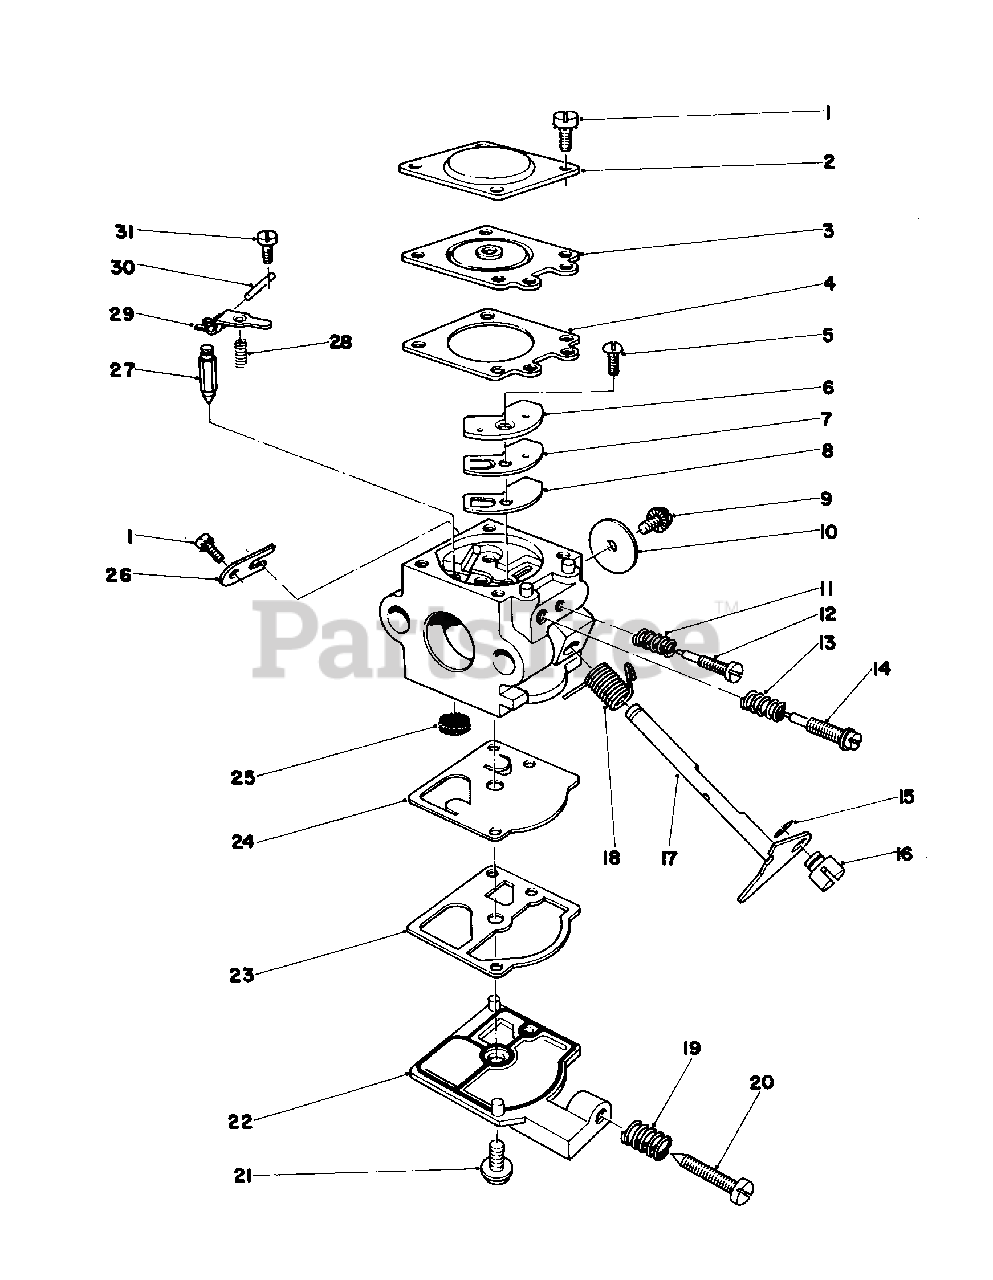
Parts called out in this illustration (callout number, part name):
2	Cover, Diaphragm
3	Diaphragm, Metering
4	Gasket, Diaphragm
5	Screw, Circuit Plate
6	Plate, Circuit
7	Diaphragm, Circuit Plate
8	Gasket, Circuit Plate
9	Screw, Throttle
10	Valve, Throttle
11	Spring, Needle-Idle
12	Idle Needle
13	Spring High Speed Needle
14	High Speed Needle
17	Throttle Shaft
18	Spring, Throttle Return
19	Spring, Idle Adjust Screw
20	Screw, Idle Adjust
21	Screw, Fuel Pump
22	Cover, Fuel Pump
23	Gasket, Fuel Pump
24	Diaphragm, Fuel Pump
25	Screen, Inlet
26	Clip, Throttle Shaft
27	Valve, Inlet Needle
28	Spring, Metering Lever
29	Lever Metering
30	Pin, Metering Lever
31	Screw Metering Lever Pin
